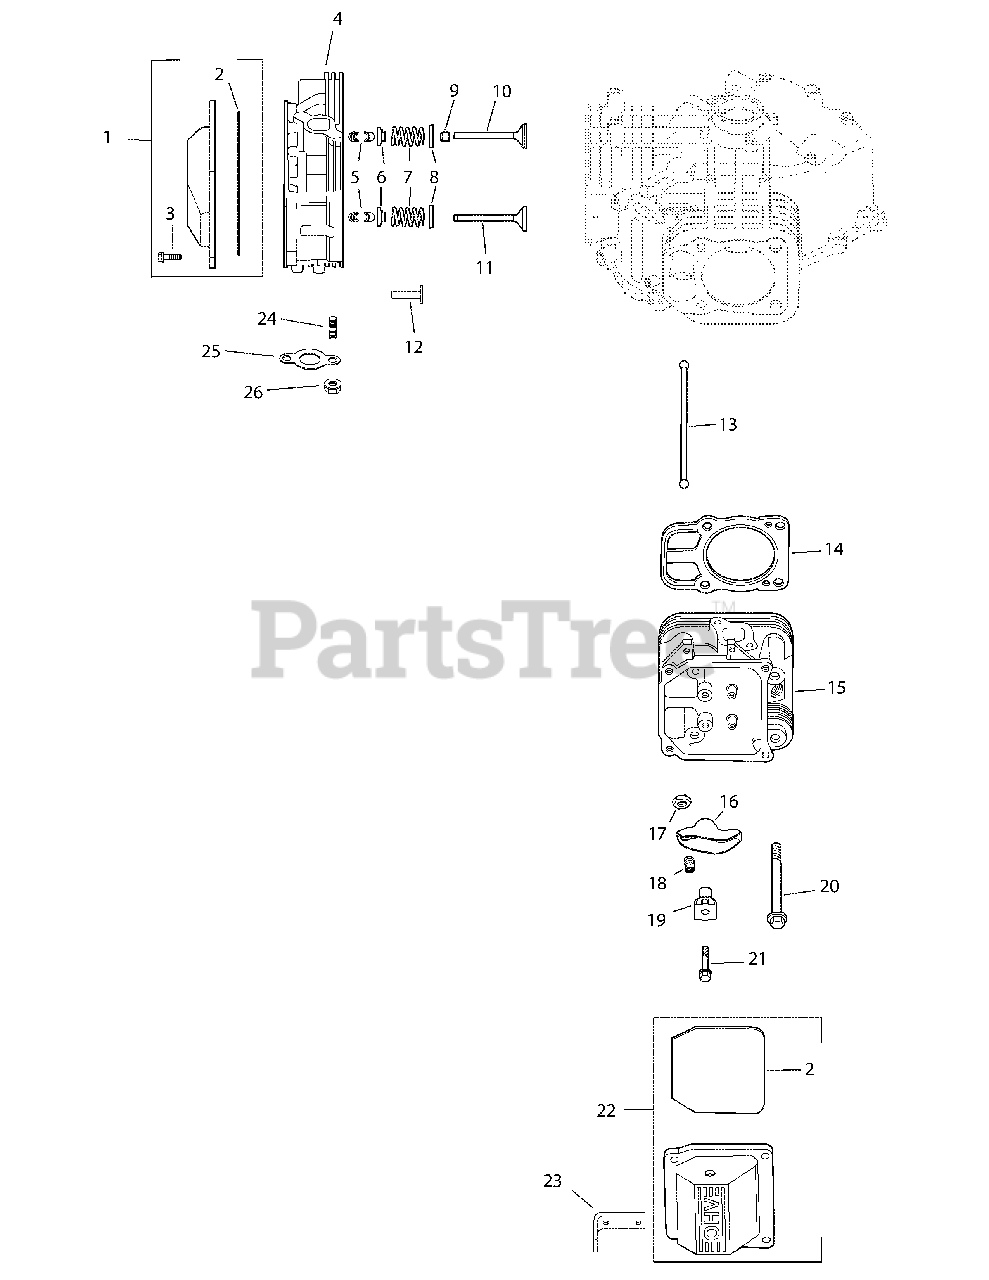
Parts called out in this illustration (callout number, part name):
1	Kit, valve cover - plain (Includes 2,3)
2	O-Ring
3	Screw, hex. flange M6x1.0x30
4	Head assembly, #1 cylinder
5	Kit, retainer
6	Cap, valve spring
7	Spring, valve
8	Retainer, spring
9	Seal, valve stem
10	Valve, intake (Std.)
11	Valve, exhaust (Std.)
12	Tappet
14	Kit, cylinder head gasket
15	Head assembly, #2 cylinder
16	Arm, rocker
17	Nut, hex. M10x0.75
19	Pivot, rocker arm
20	Screw,Hex. flange M10x1.5x90
21	Screw, hex. flange M6x1.0x45
22	Kit, valve cover - breather (Includes 2)
23	Strap, lifting
24	Stud, M8x1.25x33
25	Gasket, exhaust manifold
26	Nut, hex. flange M8x1.25
